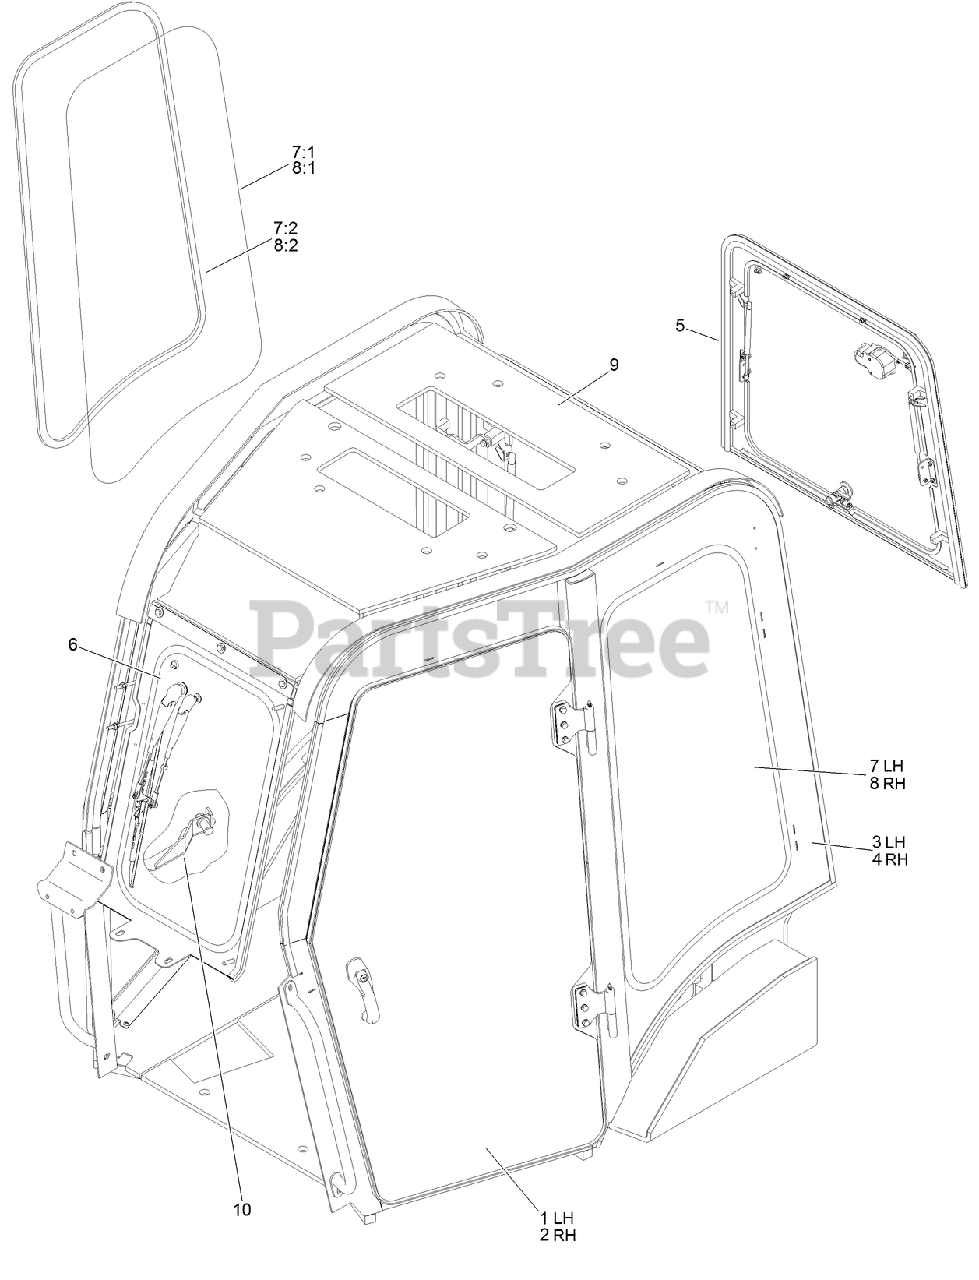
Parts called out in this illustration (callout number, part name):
1	LH DOOR ASM
2	RH DOOR ASM
3	LH SIDE PANEL ASM
4	RH SIDE PANEL ASM
5	REAR PANEL ASM
6	WINDSHIELD ASM
7	LH WINDOW ASM
7:1	GLASS-WINDOW, VENT
7:2	TRIM-SEAL
8	RH WINDOW ASM
8:1	GLASS-WINDOW, VENT
8:2	TRIM-SEAL
9	INSULATION ASM
10	DOOR HOLD OPEN KIT
